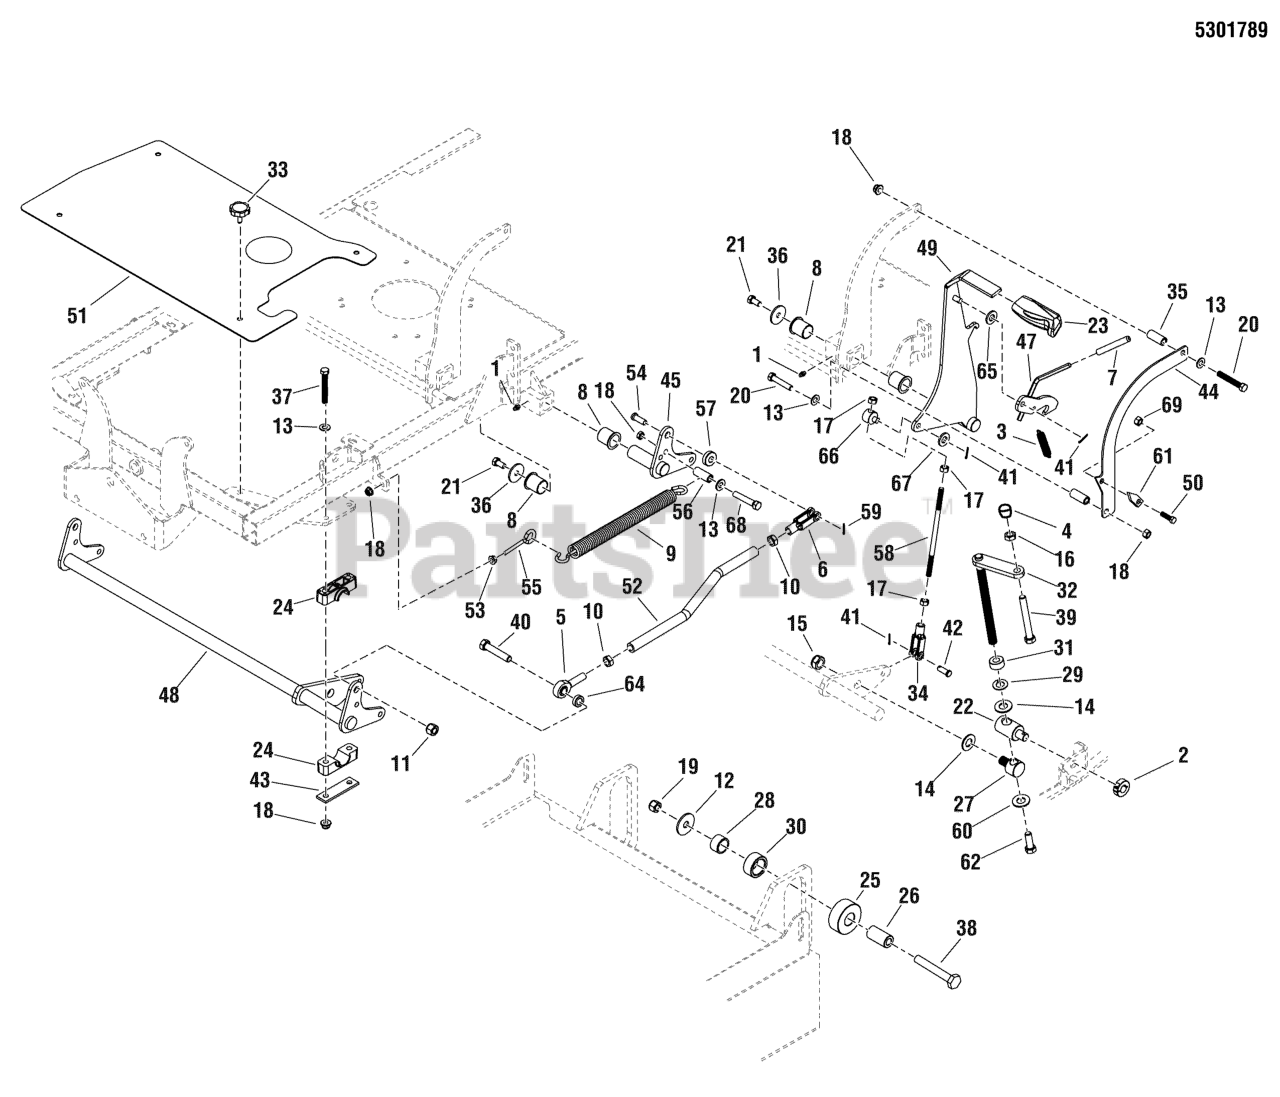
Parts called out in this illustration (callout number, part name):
1	GREASE FITTING, 1/4-28 STRAIGHT
2	COLLAR, 5/8 SPLIT
3	SPRING, EXTENSION
4	KNOB, PLASTIC, 1/2-13
5	BALL JOINT, 1/2-20, MALE
6	CLEVIS, 1/2-20, STEEL
7	COVER, VINYL HANDLE
8	BUSHING, 1.00 X 1.13 X 1.38, PLASTIC
9	SPRING, DECK LIFT ASSIST
10	NUT, 1/2-20 HEX JAM
11	NUT, Hex, Nylon Lock, 1/2-20
12	WASHER, 1/2 USS
13	WASHER, 3/8 SAE
14	WASHER, 5/8 SAE
15	NUT, 5/8-11 HEX JAM NYLON LOCK
16	NUT, 1/2-13 HEX JAM
17	NUT, 3/8-24 HEX JAM
18	NUT, 3/8-16 HEX NYLOCK FLANGE
19	NUT, Hex Flange, Nylock, 1/2-13
20	BOLT, 3/8-16 X 2, GD5, CZ
21	BOLT, 3/8-16 X 3/4, GD5, YZ WITH PATCH
22	PIVOT, SPRING ROD
23	GRIP, BLACK FLEXIBLE
24	PIVOT BLOCK, PLASTIC
25	GUIDE, DECK - TWR
26	SPACER, .52 X 1.00 X 1.88 - SS
27	PIVOT, DECK LIFT
28	BUSHING, SLEEVE, 1.00 X 1.25 X .75
29	WASHER, THRUST, .63 X 1.13 X .06
30	ROLLER, 1.256 X 1.75 X .813
31	SPACER, .64 X 1.13 X .63
32	HANDLE, CRANK, COMPACT RIDER
33	KNOB, 5/16-18 X 1.00, ROSETTE, BLK
34	CLEVIS, 3/8-24 RH, 3/8" PIN HOLE
35	SPACER, .39 X .63 X 1.00, YZ
36	WASHER, .390 X 1.38 X .109, YZ
37	BOLT, 3/8-16 X 2-3/4" GD5 CZ
38	BOLT, 1/2-13 X 3" GD5 CZ
39	BOLT, 1/2-13 X 5-1/2 GD5 YZ
40	BOLT, 1/2-20 X 2-1/4 GD5 CZ
41	PIN, 3/32 X 0.750, COT, ZINC/CLEAR
42	PIN, CLEVIS, 3/8 X 1-1/8
43	PLATE, PIVOT BLOCK SUPPORT - BLK
44	PLATE, OUTER TRANSPORT BRACKET - RED
45	WELD, BOOMER, LH - RED
46	WELD, BOOMER, RH - RED
47	WELD, DECK LOCK - RED
48	WELD, DECK LIFT SHAFT, 48 - RED
49	WELD, DECK LIFT HANDLE - RED
50	SCREW, ALLEN HEAD 1/4-20X.500 ZINC PHOS
51	GUARD, DECK TOP, EVO 52 - RED
52	ROD, DECK LIFT, EVOLUTION 48"
53	NUT, 3/8-16 HEX SERRATED FLANGE
54	CLEVIS PIN, 1/2 X 1.36 SAE STANDARD
55	EYE BOLT, 3/8-16 X 5, 2.88THRD, 1EYE, CZ
56	SPACER, .38 X .75 X 1.06, YZ
57	SPACER, .52 X 1.00 X .22, PM, CZ
58	ROD, LEVER CONNECTING
59	PIN, COTTER, 1/8 X 3/4
60	WASHER, 1/4 SAE
61	POINTER, DECK HEIGHT
62	BOLT, 1/4-20 X 3/4 GD5 YZ
63	NUT, 1/4-20 HEX NYLOCK FLANGE
64	SPACER, .52 X 1.00 X .44
65	WASHER, 3/8 GD.9 FLAT
66	ADJUSTER, BRAKE LINKAGE
67	SHIM, .375 X .625 X .031 THK
68	BOLT, 3/8-16 X 2-1/2" GD5 CZ
69	NUT, 1/4-20 HEX SERR. FLANGE
